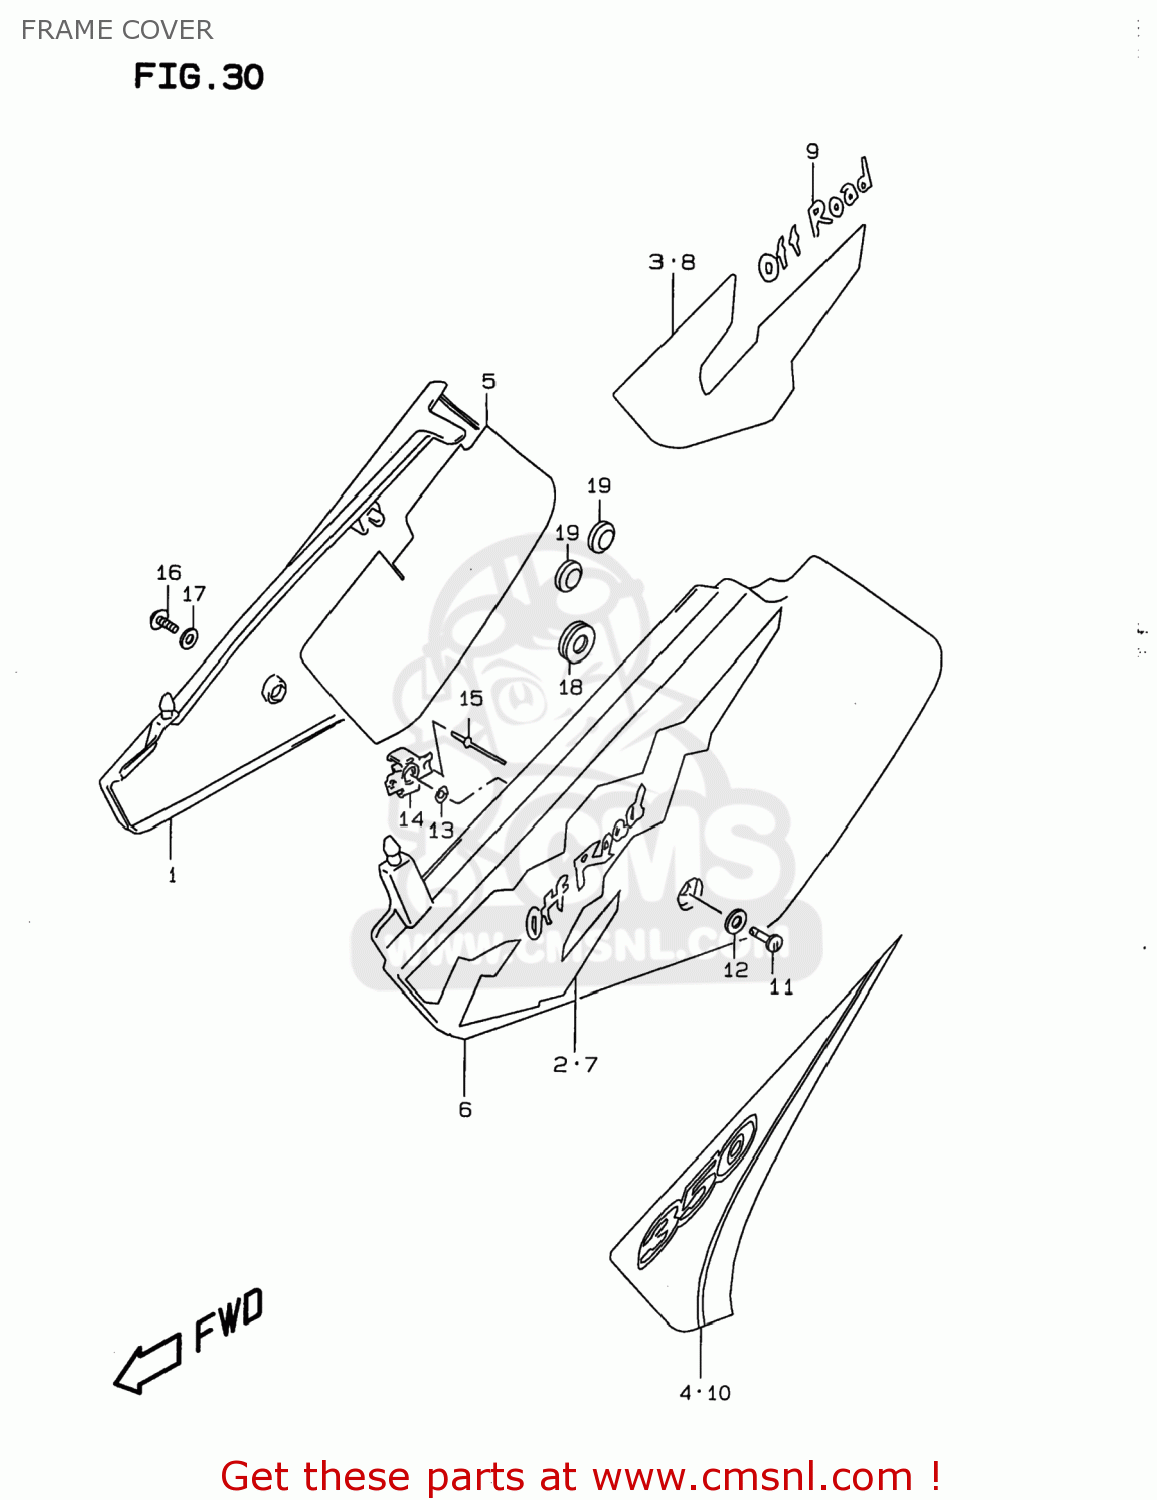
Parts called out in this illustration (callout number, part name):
1	COVER,FRAME,R(WHITE)
2	TAPE,FRAME COVER,RIGHT
3	TAPE,FRAME COVER,R
4	TAPE,FRAME COVER,R
5	SHIELD,FRAME COVER,R
6	COVER,FRAME,L(WHITE)
7	TAPE,FRAME COVER,L
8	TAPE,FRAME COVER,L
9	EMBLEM,FRAME COVER
10	TAPE,FRAME COVER,L
11	STUD
12	WASHER
13	RETAINER,FRAME COVER STUD,L
14	PLATE,FITING
15	RIVET
16	SCREW
17	WASHER
18	CUSHION
19	CUSHION
